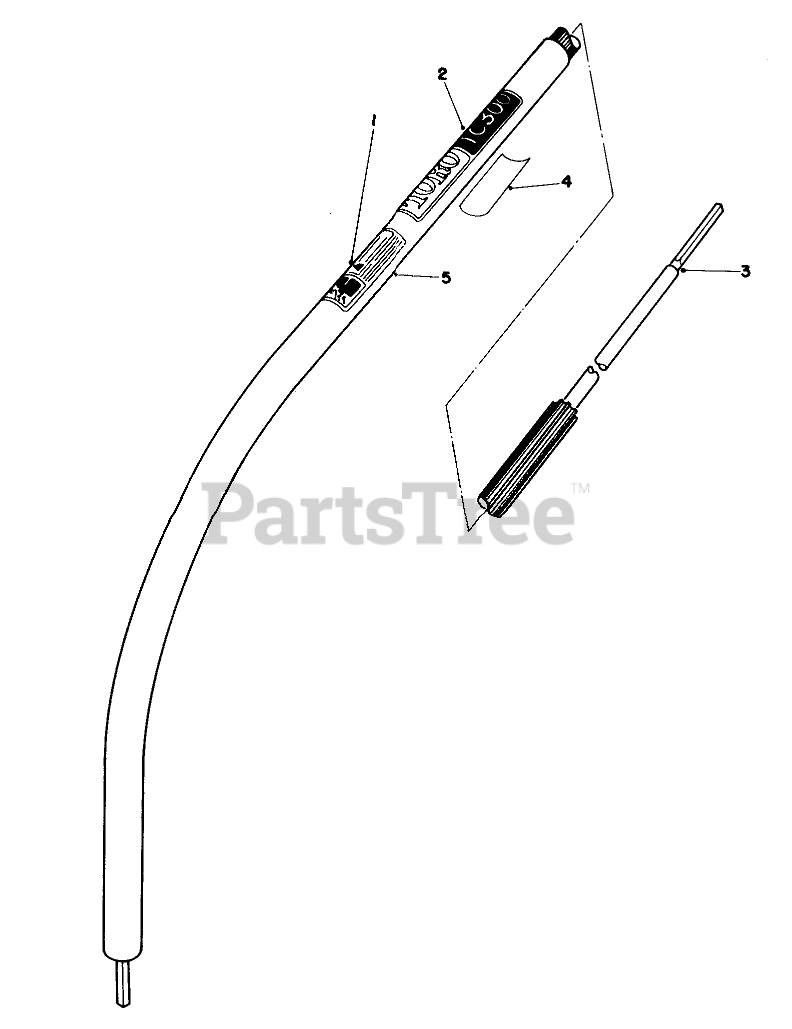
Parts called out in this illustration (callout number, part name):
1	Decal Warning
2	Decal-Toro TC 300
3	Shaft-Flex
4	REP. SERIAL PLT
5	Tube-Lower Shaft Housing (Incl. Ref. #2)
